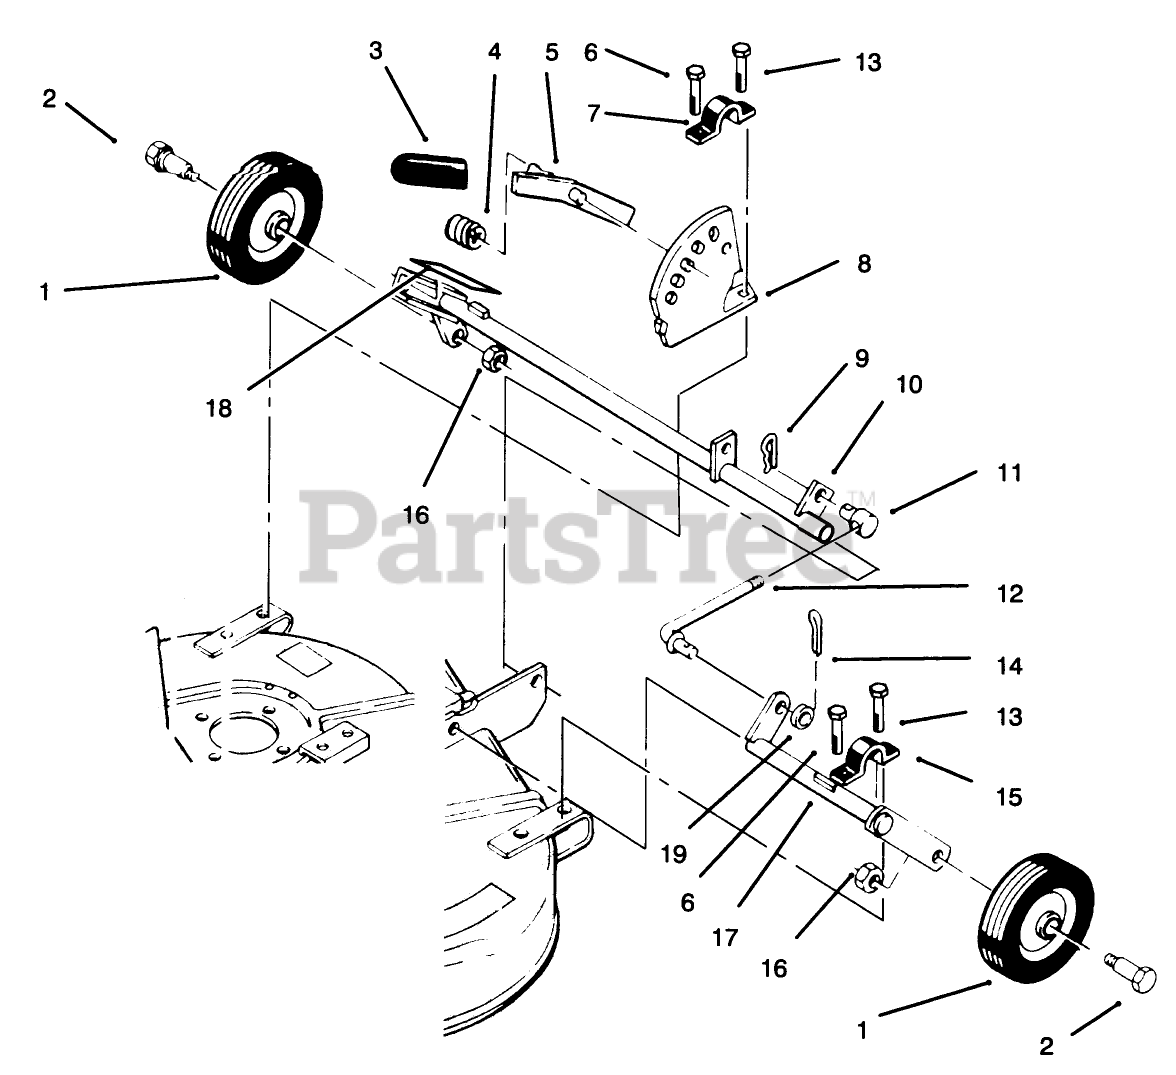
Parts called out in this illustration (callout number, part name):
1	WHEEL
2	BOLT-SHOULDER
4	SPRING-COMPRESSION
7	CLAMP
9	PIN-COTTER
12	ROD CONNECTING
13	SCREW-HWH, TAPTITE
14	PIN-COTTER
15	CLAMP *B
16	NUT-LOCK, NI
18	DECAL-HOC
19	WASHER-FLAT
